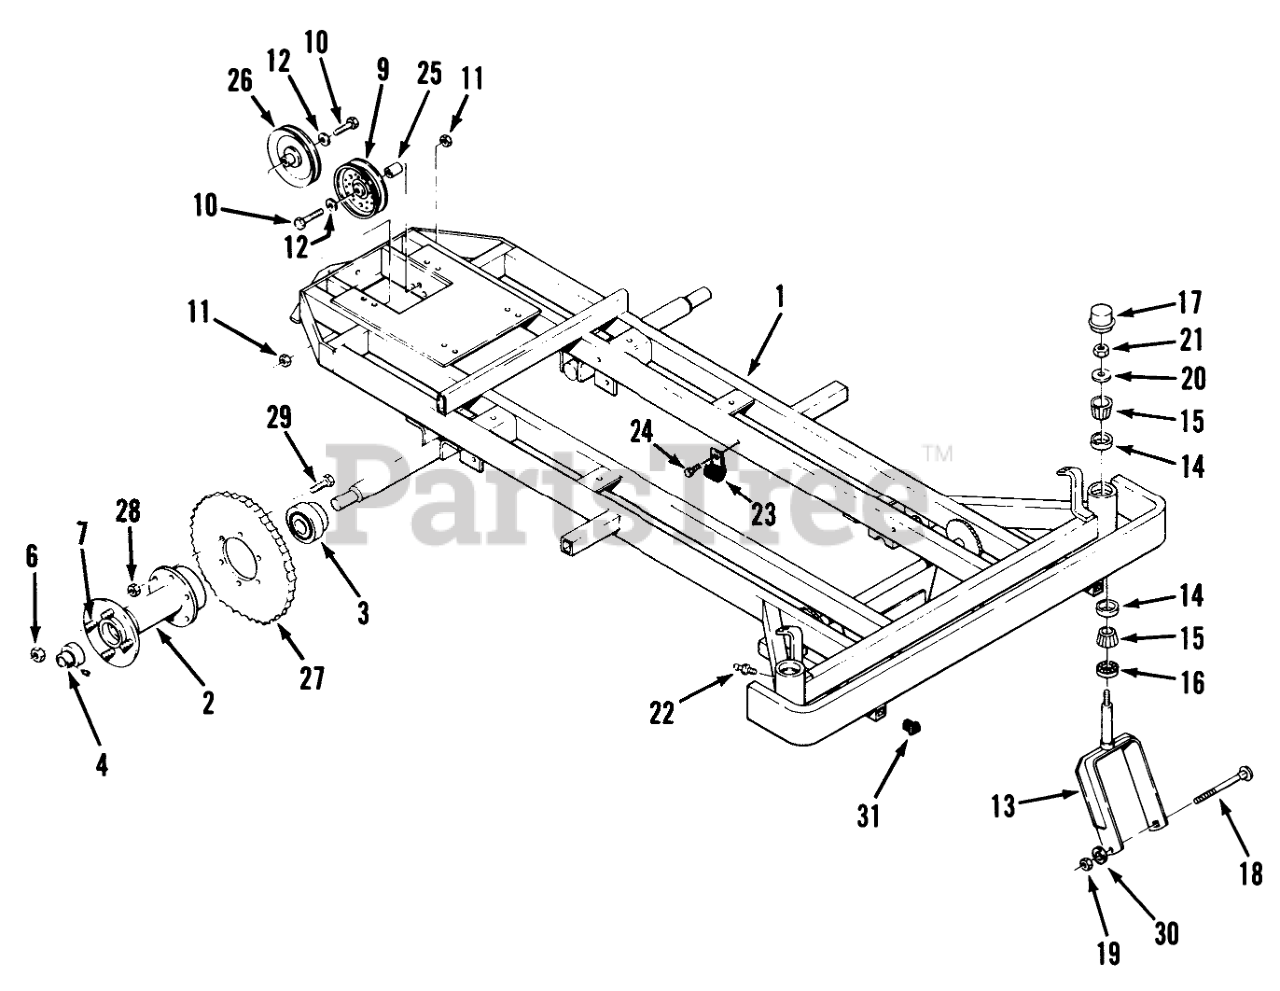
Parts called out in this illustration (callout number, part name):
1	Frame w/Bumper
2	Hub-Rear Wheel
3	BEARING-REAR AXLE
4	BEARING-REAR AXLE
6	Nut-Lug 1/2-20
7	BOLT STUD 1/2-20X1 1
9	PULLEY FLAT B
10	Bolt
11	NUT
12	Washer
13	Front Wheel Fork
14	Cup
15	Bearing
16	SEAL-FRONT WHEEL
17	DUST CAP
18	Bolt 5/8 11 x 7
19	Nut 5/8-11
20	Washer
21	Nut
22	Fitting-Grease
23	CLIP
24	Bolt
25	BUSHING
26	PULLEY-IDLER V
27	SPROCKET-REAR HUB B
28	NUT
29	Bolt
30	Lockwasher
31	PLUG-SQUARE PLASTIC
